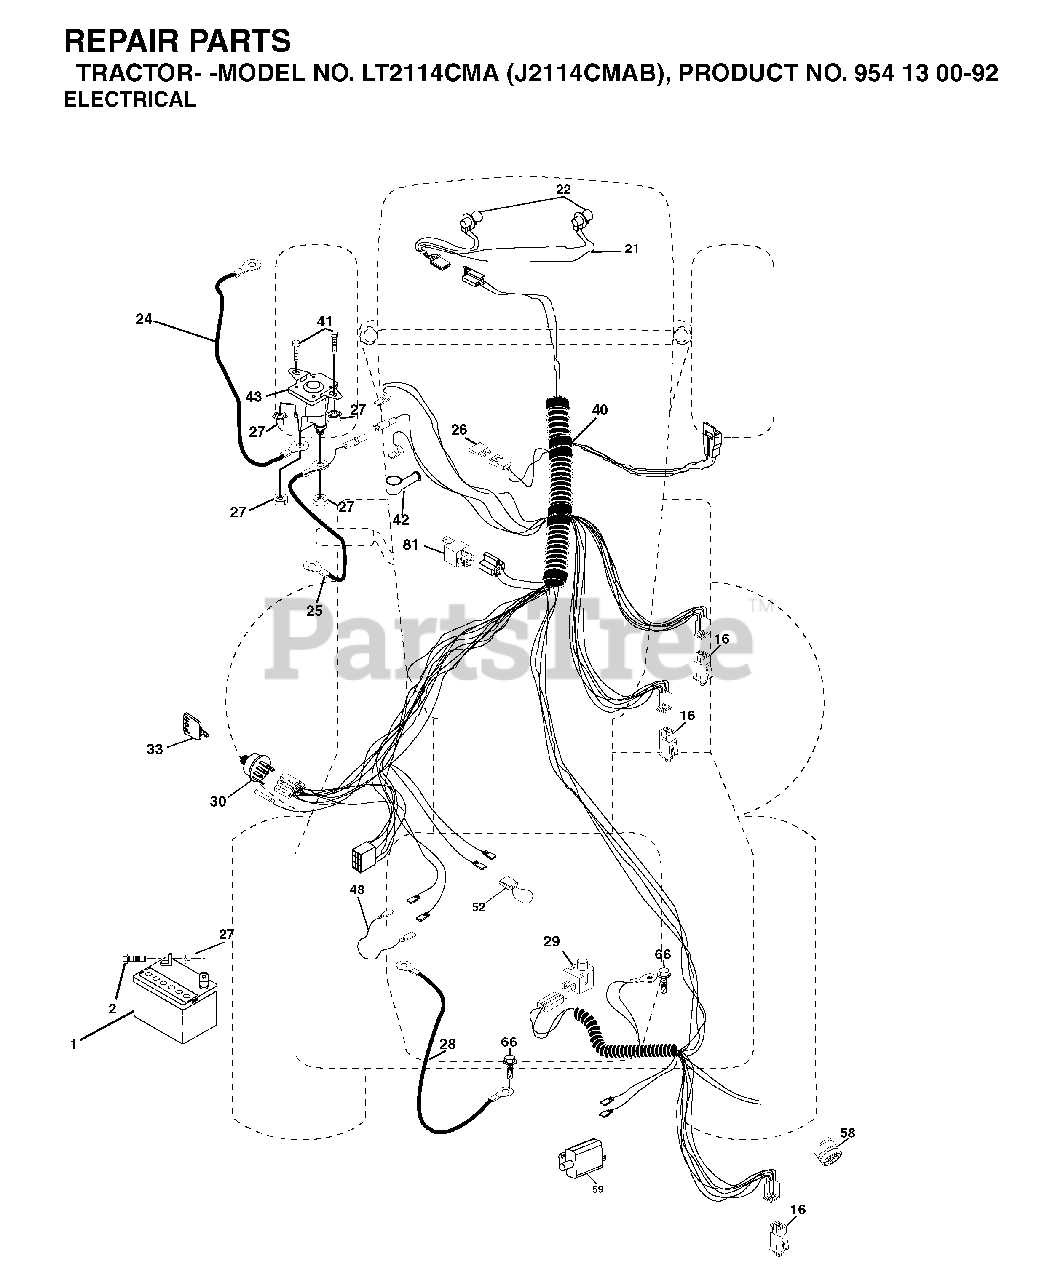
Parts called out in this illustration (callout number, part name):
1	REPL BY 532 12 38-99
16	SWITCH INTERLOOK PUSH-IN
21	HARNESS.W/LIGHT SOCKET
22	LIGHTBULB
24	BATTERY CABLE GT
25	CABLE BATTERY
26	FUSE 20AMP
27	NUT
28	CABLE GROUND
29	PLUNGER SWITCH (COLOR:OLIVE)
30	IGNITION SWITCH
33	KEY MLD GEN DELTA
42	TERMINAL COVER
43	SOLENOID
52	WIRE PROTECTION LOOP
58	BUZZER
81	RELAY.ASSY.T
